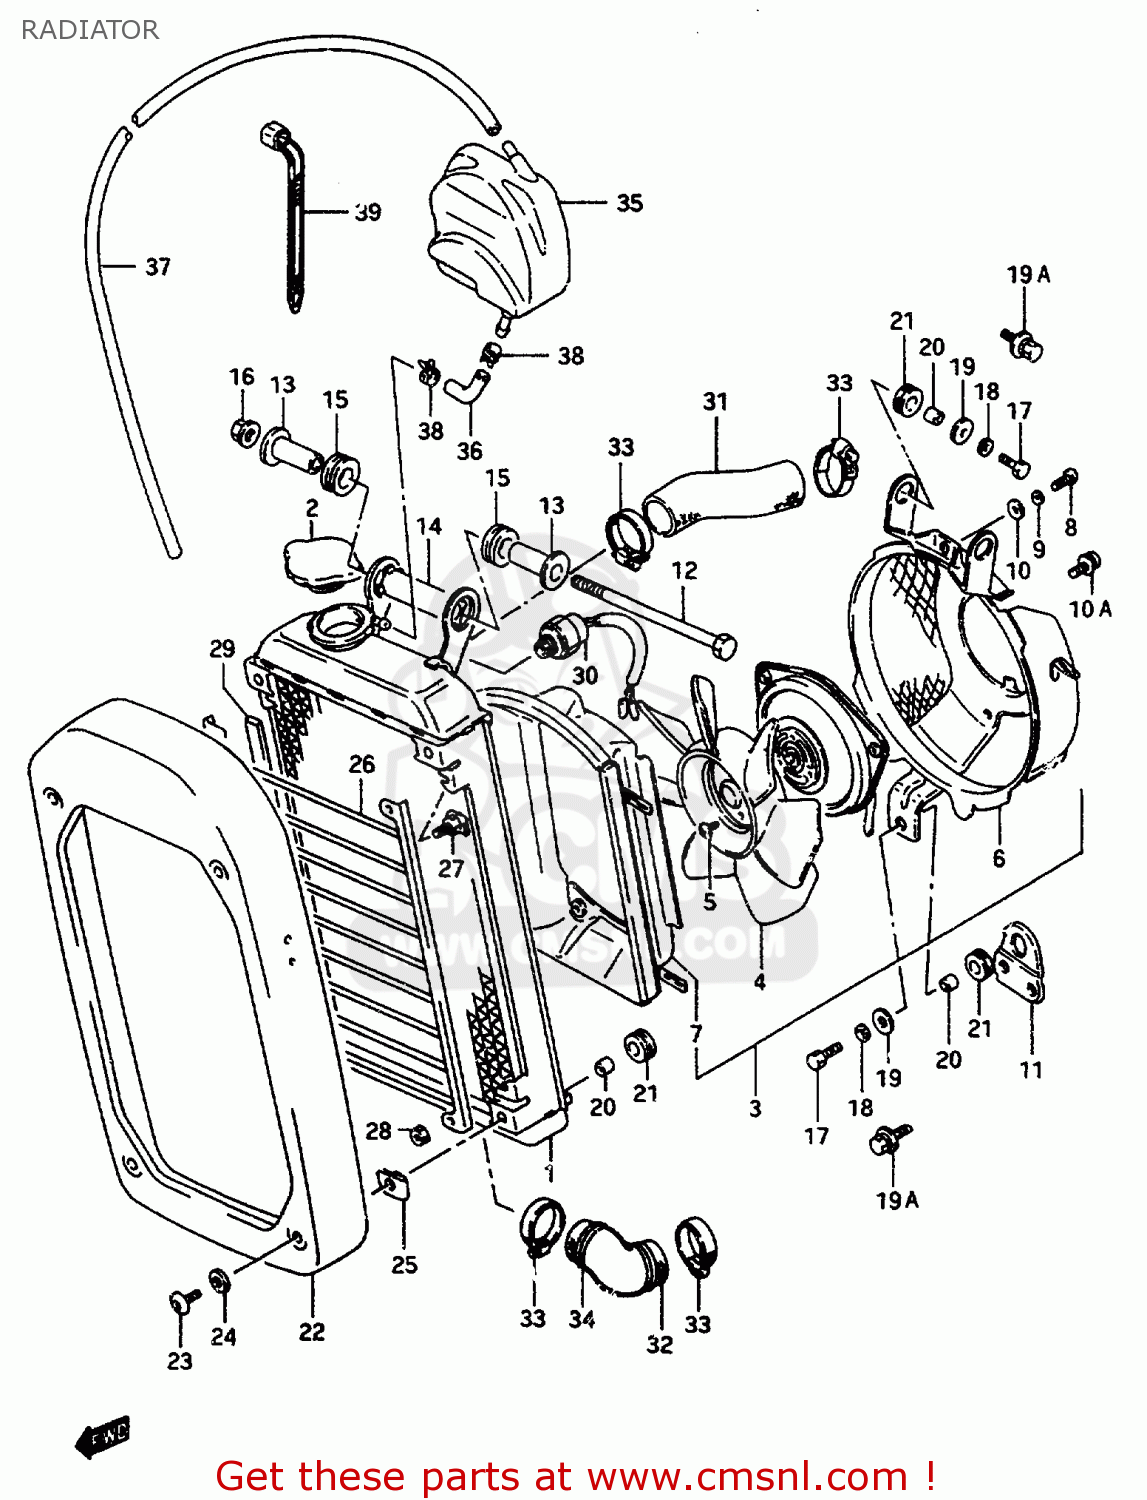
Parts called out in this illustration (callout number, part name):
1	RADIATOR ASSY,WATER
2	CAP,RADIATOR
3	FAN ASSY,RADIATOR
4	FAN
5	SCREW 4X6
6	SHROUD,FAN
7	DUCT,FAN
8	SCREW
9	LOCK,WASHER
10	WASHER
10A	SCREW
11	BRACKET,RADIATOR FAN
12	BOLT 10X135
13	SPACER,RADIATOR CUSHION NO.2
14	SPACER,RDTR CUSH NO.2 OUTER
15	CUSHION
16	NUT 10MM
17	BOLT 6X16
18	WASHER,LOCK
19	WASHER (6.5X18X1.6)
19A	BOLT
20	SPACER (6X9X8)
21	CUSHION
22	COVER,RADIATOR
23	SCREW(6X10)
24	WASHER (6.2X14X2)
25	NUT,RADIATOR COVER
26	BUMPER,RADIATOR
27	BOLT
28	NUT
29	CUSHION,RADIATOR BUMPER
30	SWITCH,RADIATOR FAN
31	HOSE,RADIATOR INLET
32	HOSE,WATER PUMP OUTLET
33	CLAMP
34	SPRING
35	TANK,RESERVOIR
36	HOSE,RESERVE TANK INLET
37	HOSE,RESERVOIR TANK OUTLET
38	CLIP
39	CLAMP(L:125)
